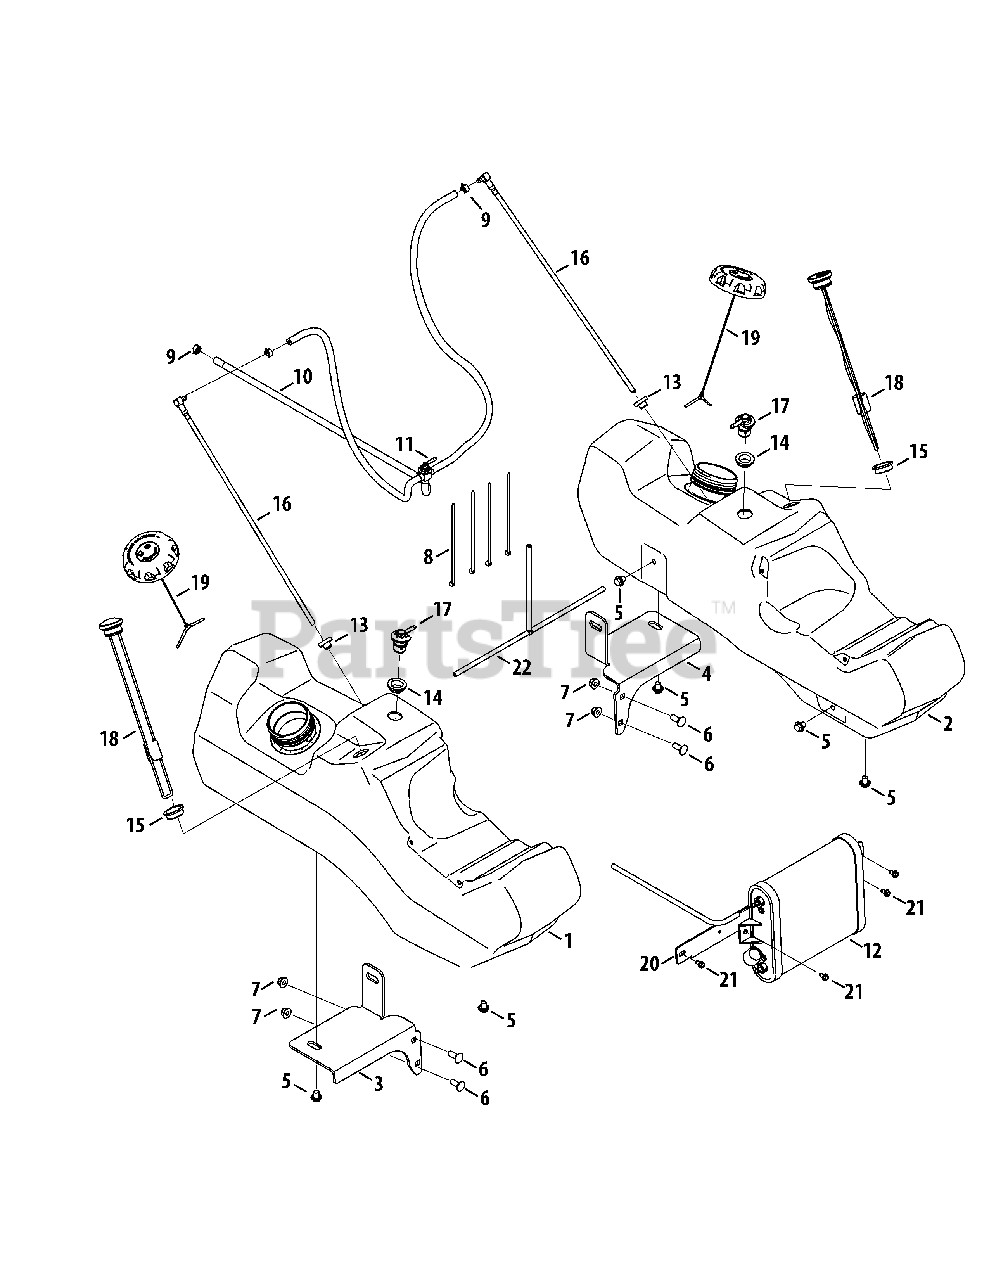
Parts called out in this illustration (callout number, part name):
1	Fuel Tank Assembly, RH
2	Fuel Tank Assembly, LH
3	Rear Fuel Bracket, RH
4	Rear Fuel Bracket, LH
5	Hex Cap Screw, 3/8-16 x .500
6	Carriage Bolt, 3/8-16 x .500
7	Nut, 3/8-16, Flangelock
8	Cable Tie
9	Hose Clamp, .500 Dia.
10	Fuel Hose., 1/4
11	Fuel Switch
12	Carbon Canister
13	Grommet, Fuel Tank
14	Rubber Grommet
15	Grommet, 1.58 OD x 1.21 ID x .5
16	Fuel Pickup Valve
17	Fuel Rollover Valve
18	Fuel Gauge
20	Canister Bracket
21	Screw, 1/4-20 x .500
22	Fuel Hose Assembly
22	Tee Fitting, Fuel
